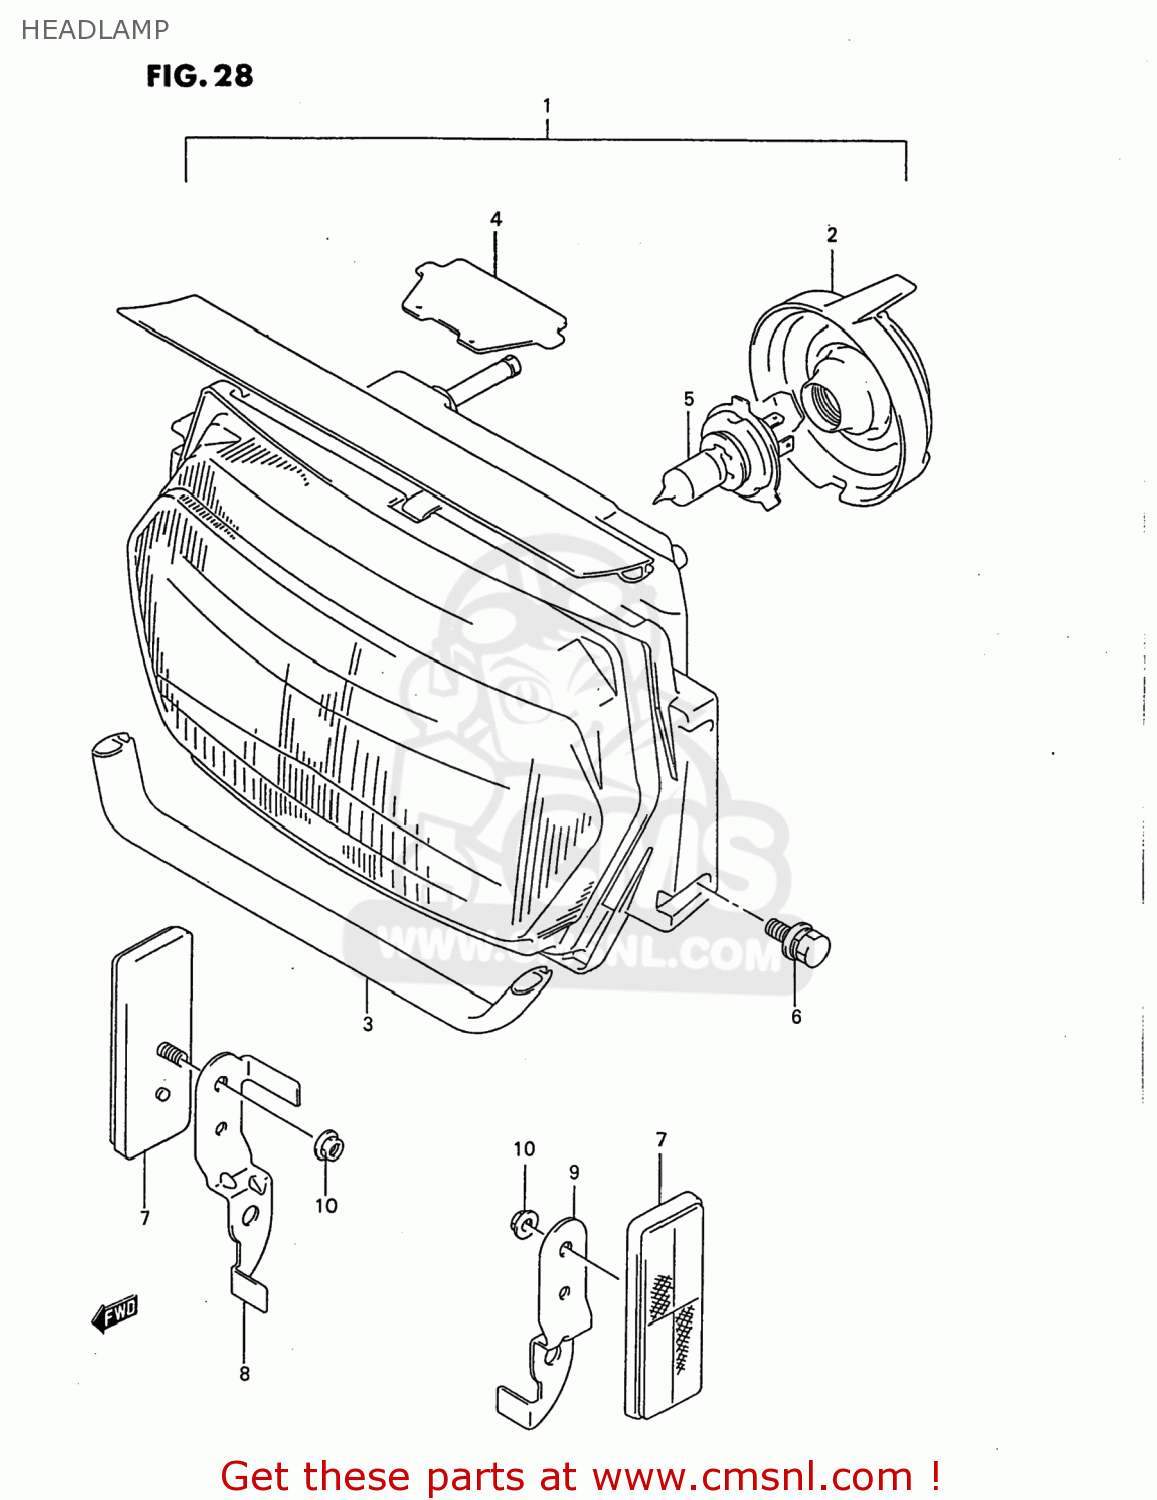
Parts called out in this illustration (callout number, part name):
1	HEADLAMP ASSY
2	COVER,SOCKET
3	GASKET,HEADLAMP (NAS)
4	GASKET (NAS)
5	BULB(12V60/55W,H4)
6	BOLT, REAR
7	REFLEX REFLECTOR,FR SIDE
8	BRACKET,FR SIDE RR,R
9	BRACKET,FR SIDE RR,L
10	NUT
